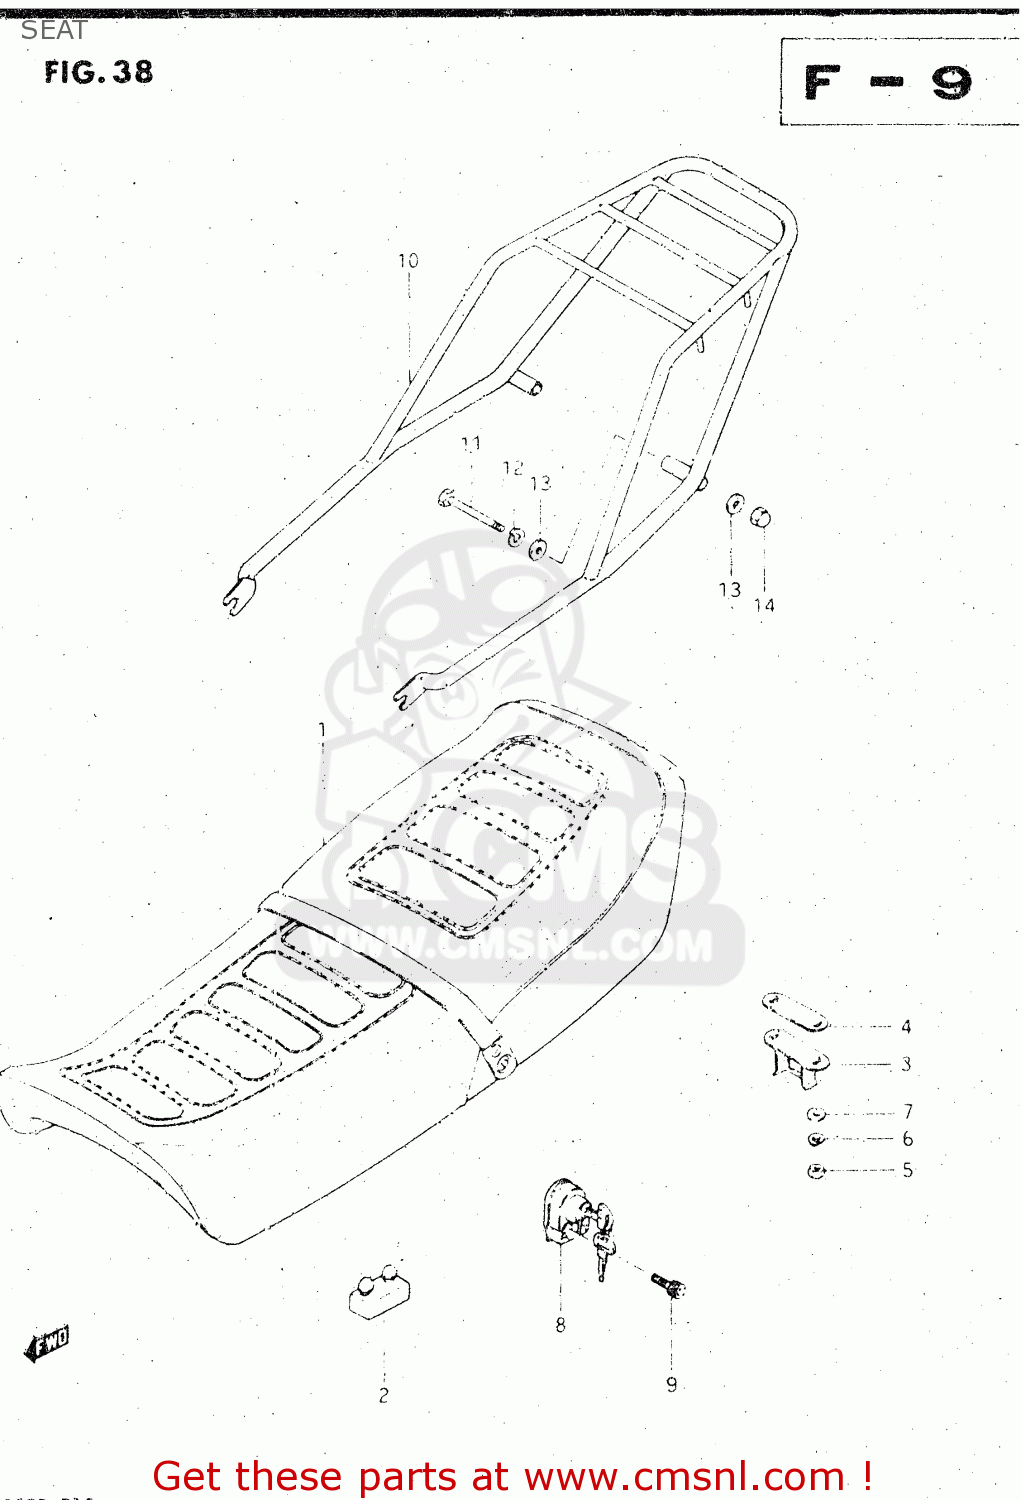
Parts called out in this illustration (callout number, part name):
1	SEAT (BLACK)
2	CUSHION
3	STRIKER,SEAT LOCK
4	SHIM,SEAT LOCK STRIKER
5	NUT 6MM
6	LOCK WASHER
7	WASHER
8	LOCK ASSY,HELMET
9	BOLT 5X25
10	CARRIER
11	BOLT 8X105
12	LOCK WASHER
13	WASHER
14	NUT
